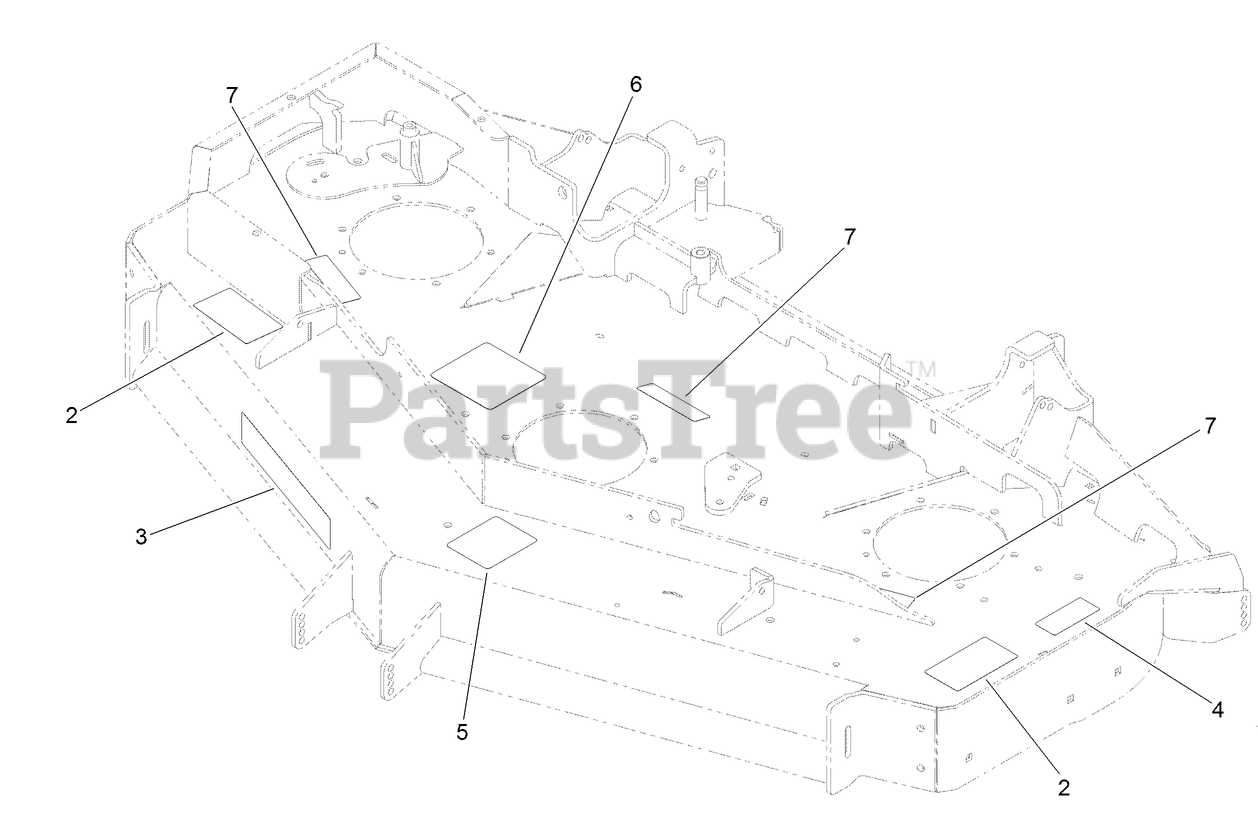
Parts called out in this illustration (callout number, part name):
2	DECAL-DANGER
4	DECAL-BOLT TORQUE
5	DECAL-ROLLER, ANTI-SCALP
6	DECAL-ROUTING, DECK BELT
7	DECAL-COVER, MISSING
